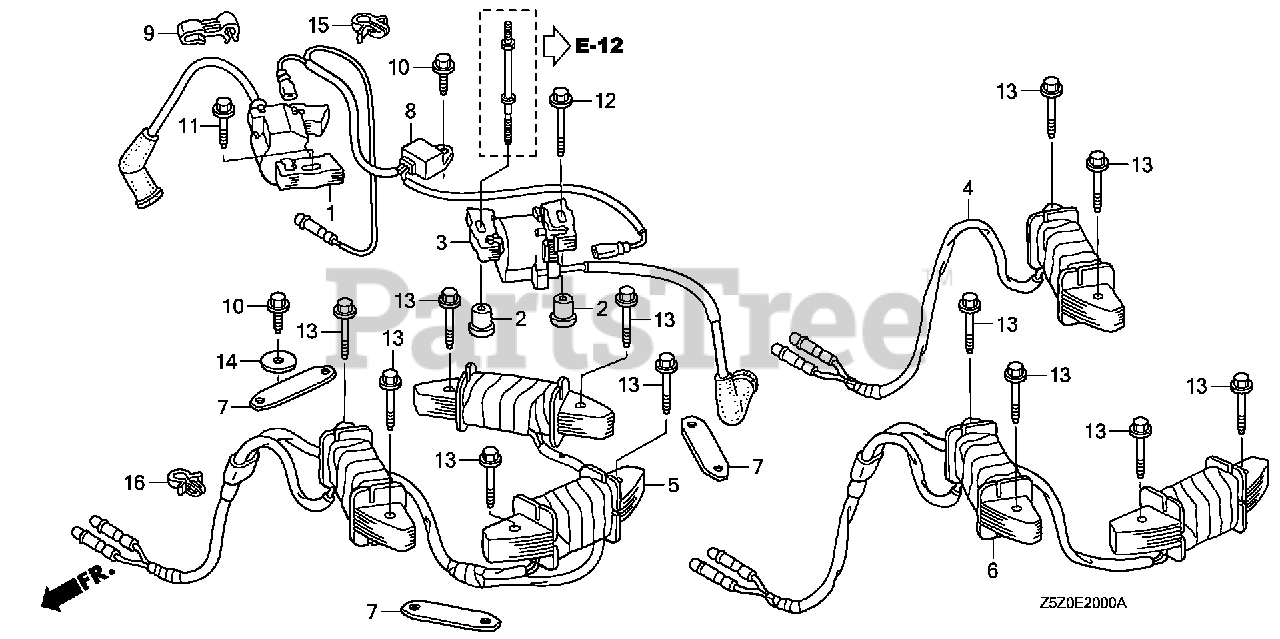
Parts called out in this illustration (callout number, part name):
1	COIL ASSY., IGNITION (#1)
2	COLLAR, IGNITION COIL
3	COIL ASSY., IGNITION (#2)
4	COIL ASSY., CHARGE (12V/3A)
8	DIODE ASSY., ENGINE STOP
9	CLAMP, CENTER WIRE
10	BOLT, FLANGE (6X12) (CT200)
11	BOLT, FLANGE (6X28) (CT200)
12	BOLT, FLANGE (6X45) (CT200)
13	BOLT, FLANGE (6X32) (CT200)
14	WASHER, TANK SETTING
15	CLIP, WIRE HARNESS (6MM) (WHITE)
16	CLIP, WIRE HARNESS
